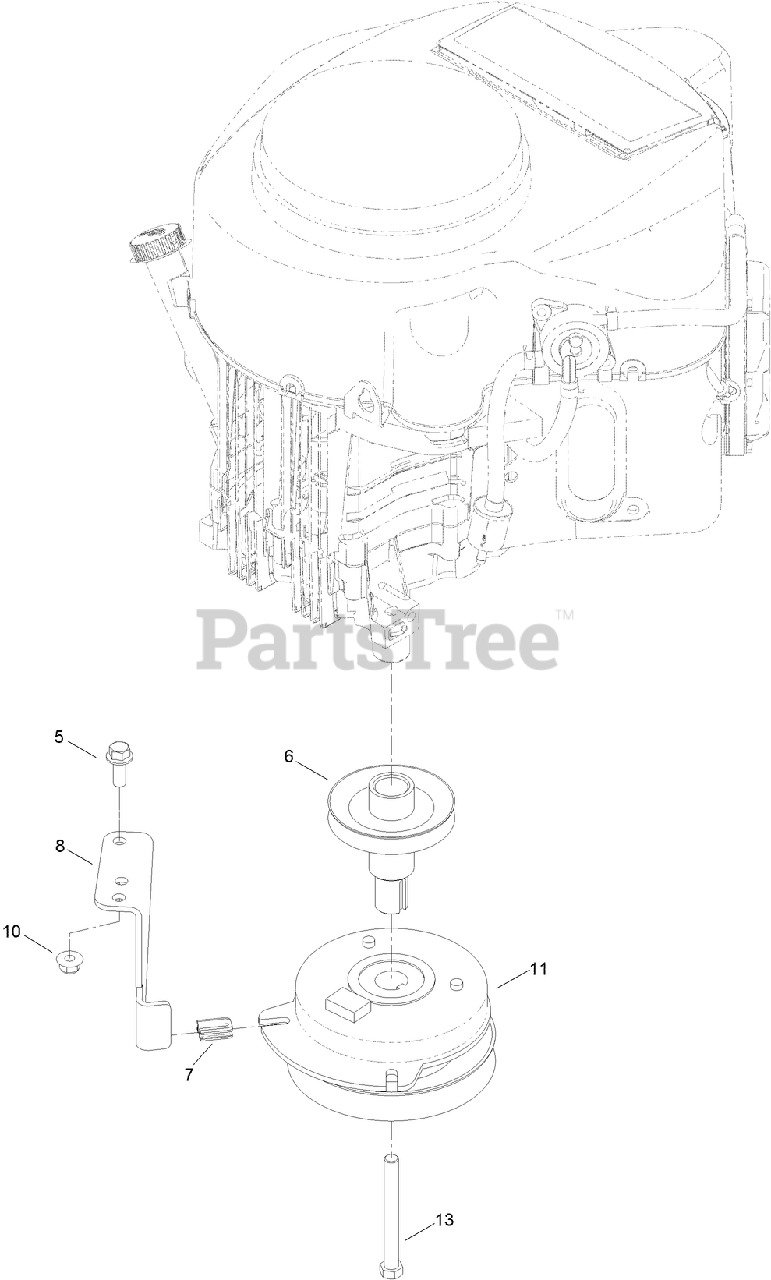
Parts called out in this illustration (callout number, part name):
5	SCREW-HHF
6	PULLEY-ENGINE
7	ISOLATOR-CLUTCH
8	STOP-CLUTCH
10	NUT-HF, NI
11	CLUTCH-ELECTRIC, PTO
13	SCREW-HH
